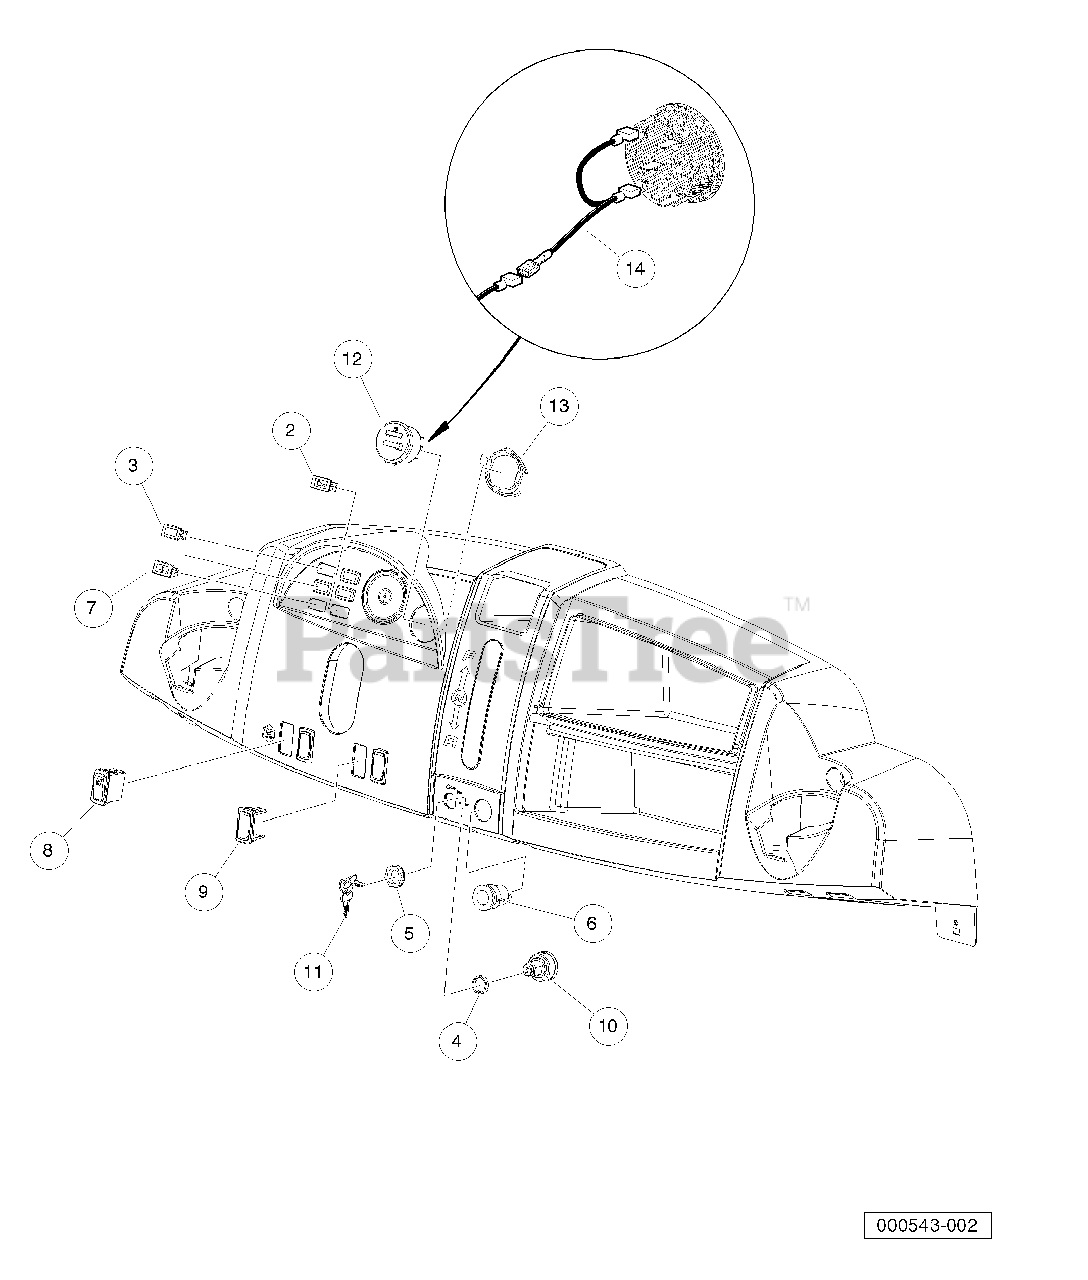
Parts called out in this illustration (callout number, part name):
1	Instl, Elec Sys, Restyle Diesl
2	Light, Oil
3	Plug, Hole
4	Spacer, Keyswitch
5	Nut, Key Switch
6	Receptacle, Accessory
7	Light, Indicator, Coolant Temp
8	Switch, Rocker, Light
9	Cover, Hole, Switch, Rocker
10	Keyswitch, 12v, Diesel
11	Keys
12	Gauge Fuel-hour Sep Gnd
13	Clip, Meter, Round
14	Asm Wire Meter F-h Jumper
